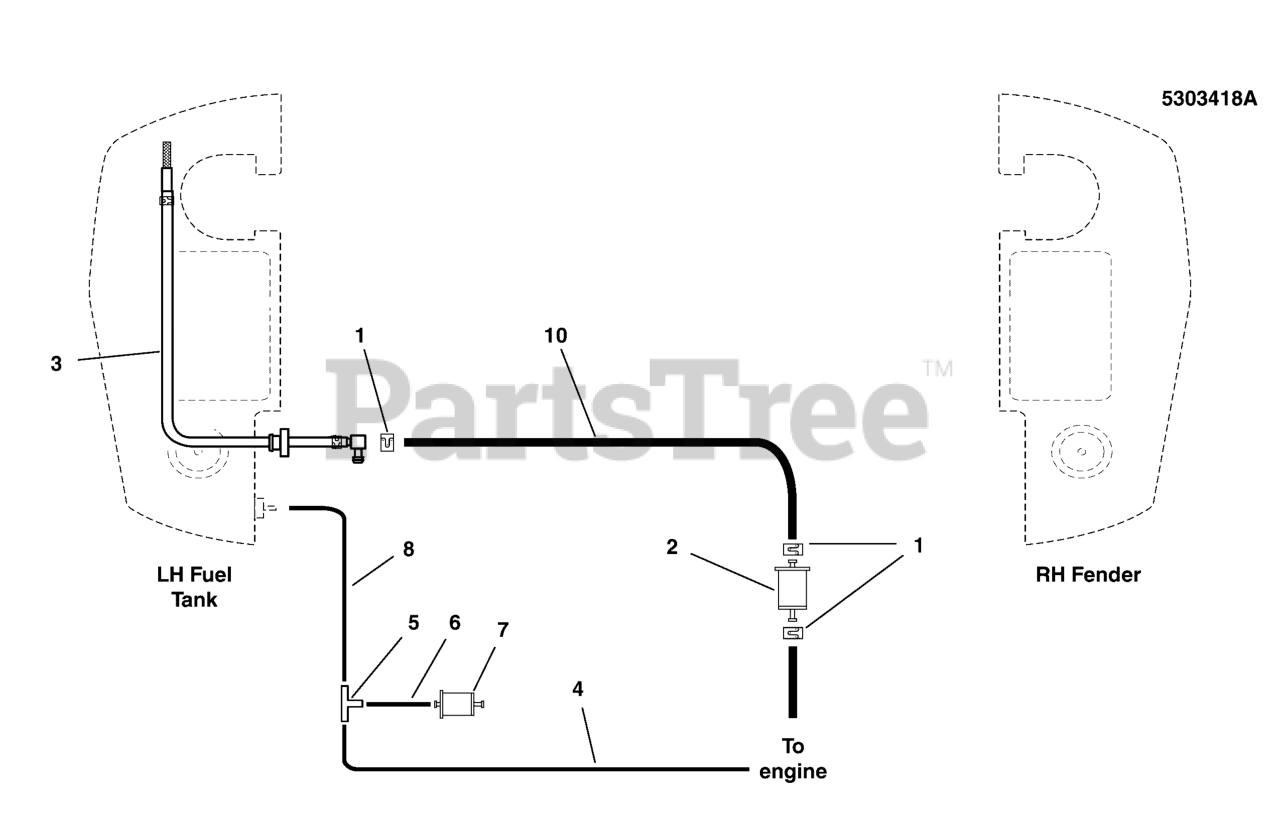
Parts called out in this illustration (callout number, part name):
1	CLAMP, Hose
2	FUEL FILTER (SV)
3	ASSM, FUEL HOSE, 26
4	HOSE, VAPOR, 5MM ID, 34.00 LG
5	FITTING, 3/16" TEE, B
6	HOSE, VAPOR
7	FILTER, FUEL
8	HOSE, VAPOR, 5MM ID, 9.00 LG
10	HOSE, 1/4" FUEL, 24.0
